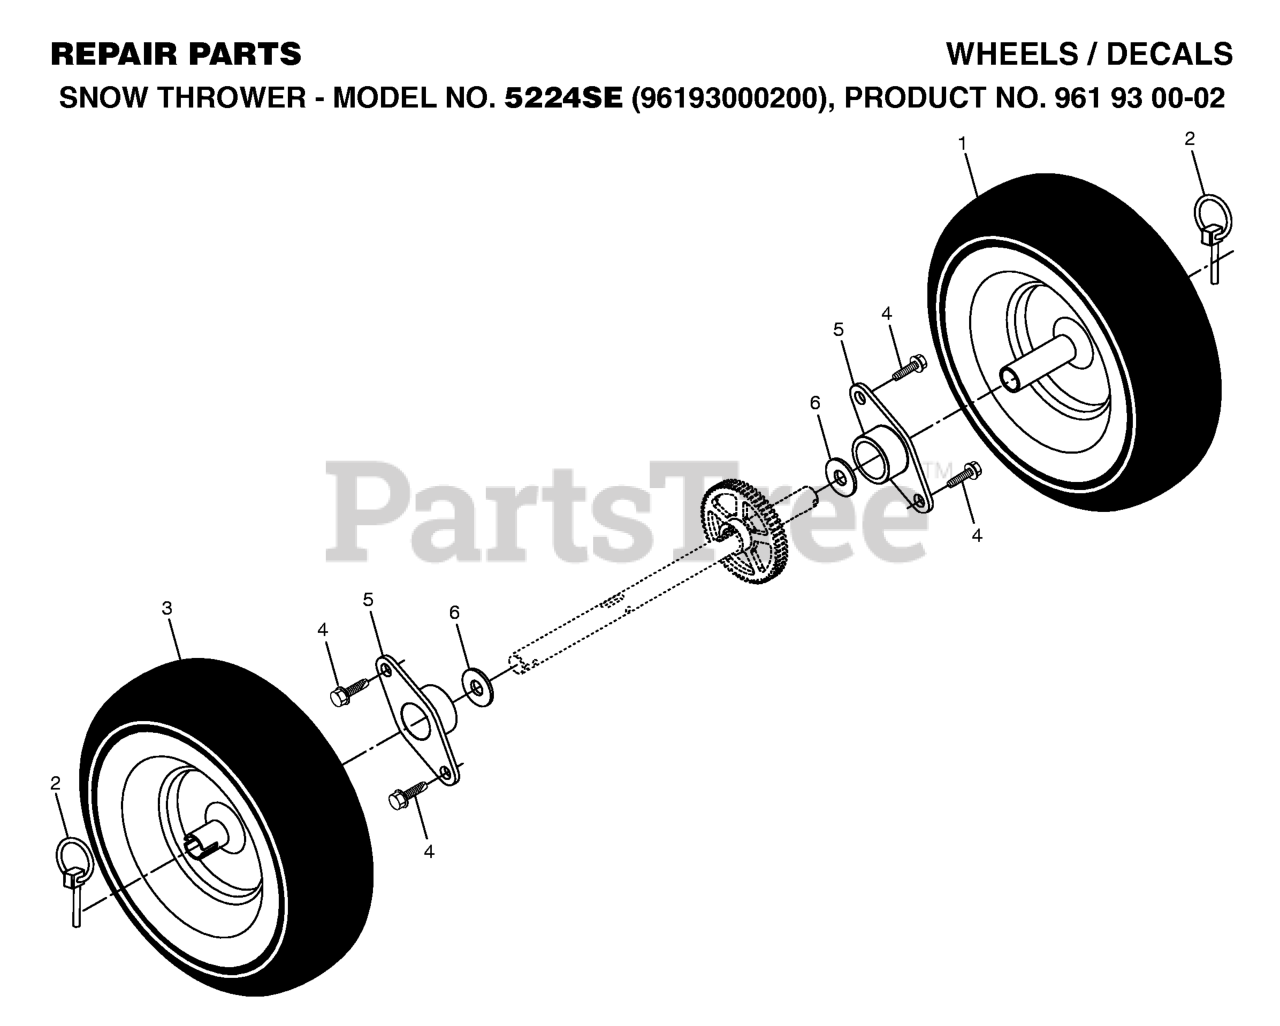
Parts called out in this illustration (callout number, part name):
1	WHEEL ASSY 13" LH
2	PIN KLIK, 1/4
3	WHEEL.ASM.RT.13".GRAY.XTRAC
5	BEARING, AXLE
6	WASHER TRUST 1"
